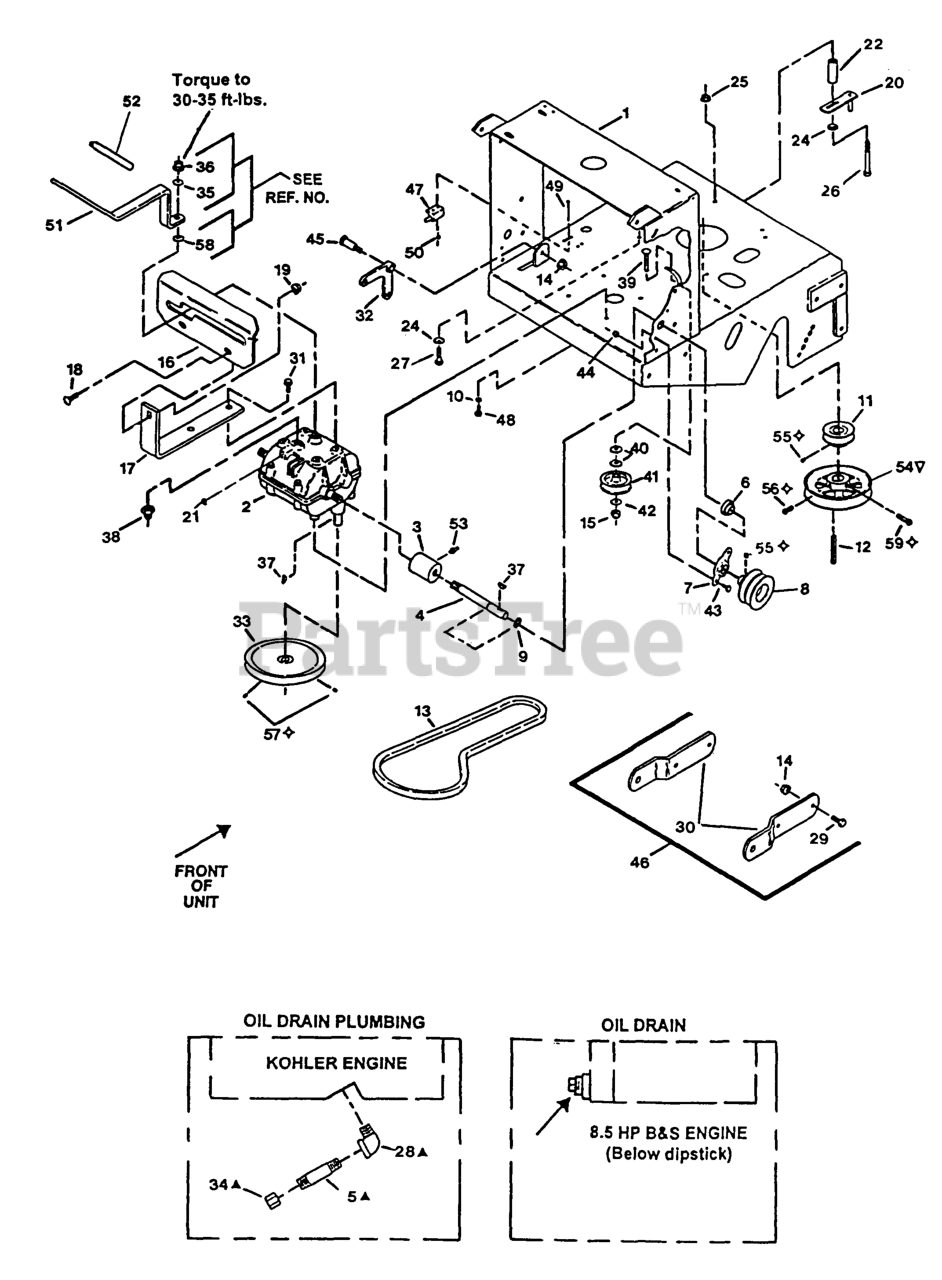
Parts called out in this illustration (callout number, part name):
1	Rear Deck
4	SHAFT-TRANSMISSION
5	NIPPLE
6	BEARING-SHAFT
7	FLANGE-OUTPUT
10	WASHER-LOCK
11	SHEAVE-TRANSMISSION
12	KEY,MACH 1/4X1/4X2-5/8
13	BELT,TRANS DRIVE
17	BRACKET-PLATE, SHIFT
20	GUIDE-BELT
21	BALL,DETENT (SERVICE ONL
23	KIT,TRANSMISSION UPDATE
24	WASHER-SPRING
28	FITTING-ELBOW-90
30	HITCH-SULKY
32	BELLCRANK
33	SHEAVE-TRANSMISSION
34	CAP-HEX
38	SWITCH-START, NEUTRAL
45	BOLT-SHOULDER
46	Sulky Hitch Kit, Metro
47	SWITCH-OPEN, NORMALLY
54	SHEAVE,BLADE DRIVE
55	SCREW-SET
56	SCREW-SET
